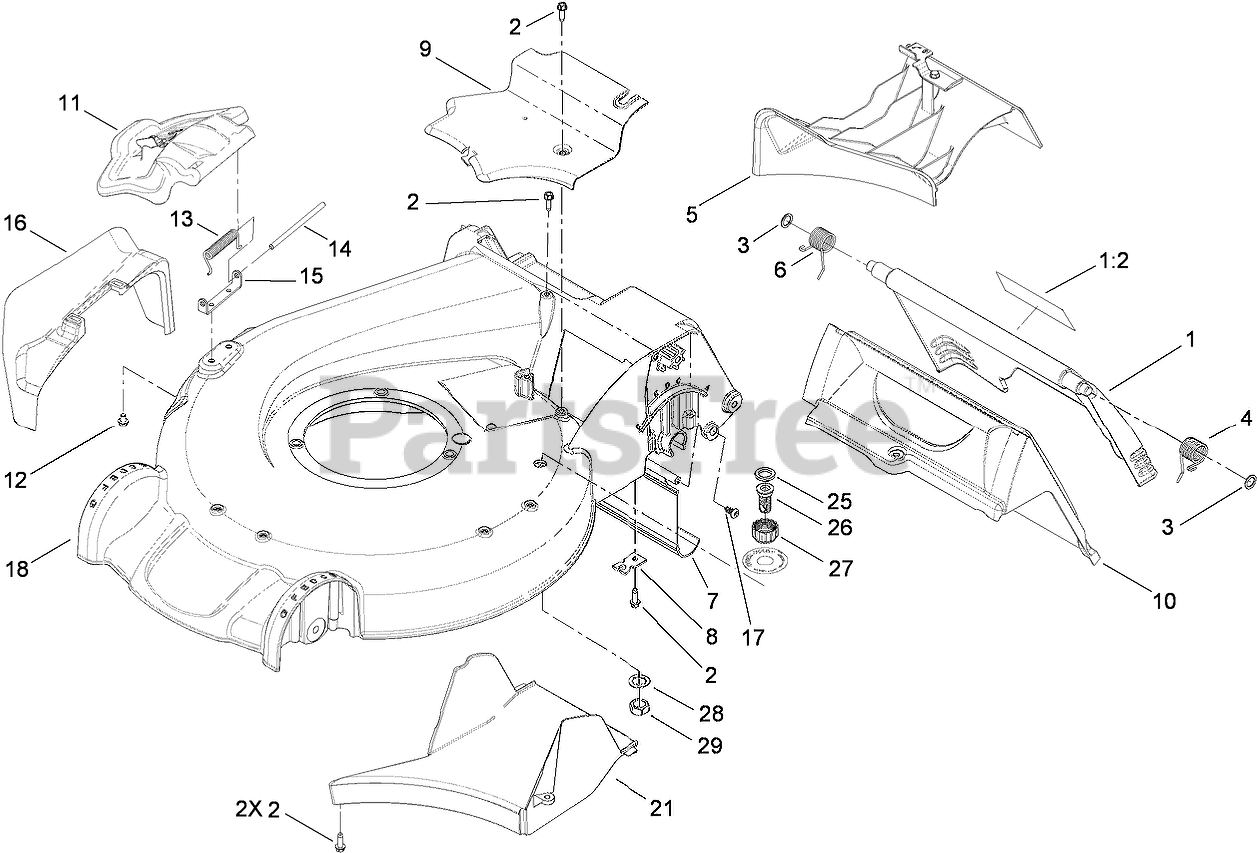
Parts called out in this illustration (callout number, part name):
1	REAR DOOR ASM
1:2	DECAL-WARNING
2	SCREW-HWHTF
3	WASHER-NYLON
4	SPRING-TORSION
5	MULCH PLUG ASM
6	SPRING-TORSION
7	SHIELD-TRAILING
8	BRACKET-CABLE, TRACTION
9	COVER-BELT
11	DISCHARGE DOOR ASM
12	SCREW-HWH
13	SPRING-TORSION
14	ROD-COVER
15	BRACKET-COVER
16	CHUTE-DISCHARGE, SIDE
17	SCREW-PTH
18	HOUSING ASM
21	TUNNEL-DISCHARGE
25	WASHER-SEAL, WASHOUT PORT
26	PORT-WASHOUT
27	COUPLING-HOSE, WASHOUT PORT
28	WASHER-TOOTH, INTERNAL
29	NUT-JAM
